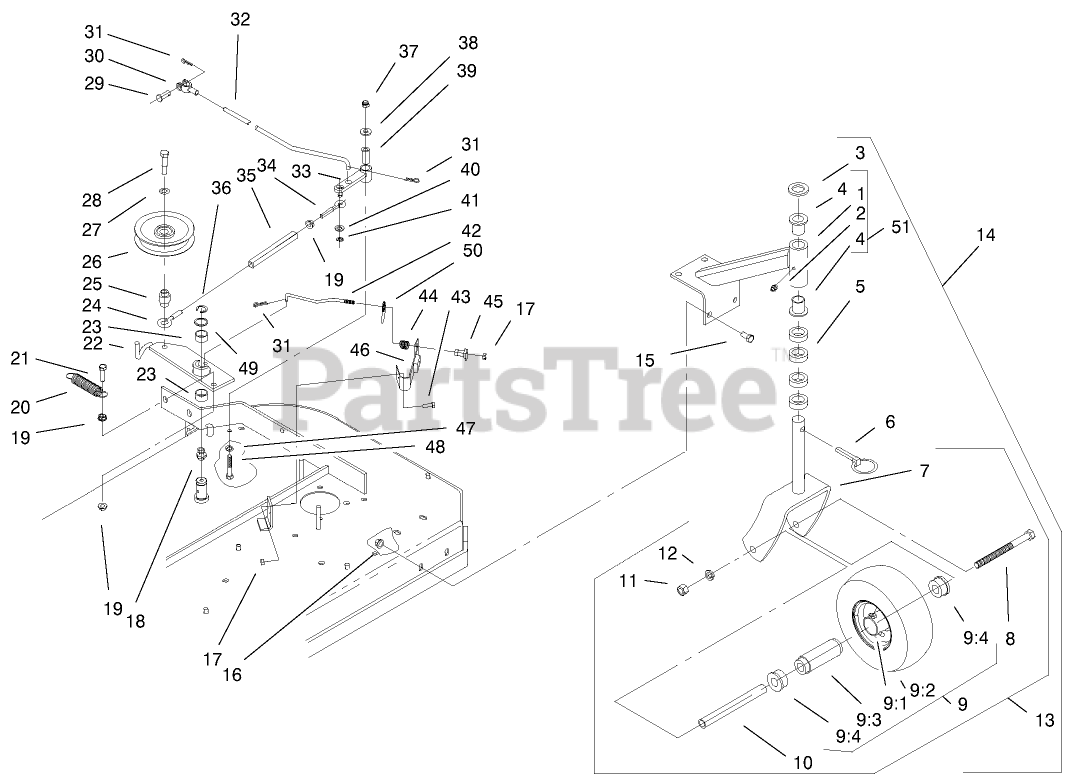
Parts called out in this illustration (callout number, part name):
1	Support-Caster
2	FITTING-GREASE
3	Washer
4	Bearing-Flanged
5	Spacer
6	Pin
7	Fork
8	SCREW-HH
9	Tire/Wheel ASM
9:1	Wheel Hub ASM
9:2	Tire
9:3	Bearing
9:4	Bushing
10	Spacer
11	NUT-HH
12	WASHER-LOCK
13	Caster Wheel ASM
14	Caster/Mount ASM
15	SCREW-HH
16	NUT-HHF, WHIZ
17	NUT-LOCK, NI
18	FITTING-GREASE
19	NUT-HF
20	Spring
21	SCREW-HH
22	Engagement Arm w/Bushings
23	Bearing-Sleeve
24	Eye Bolt
25	Bushing
26	Pulley-Idler
27	Washer
28	SCREW-HH
29	Pin-Clevis
30	Yoke
31	PIN-COTTER
32	Linkage-Assist Arm
33	Assist Arm ASM
34	Eye Bolt
35	Turnbuckle Body
36	RING-RETAINING, EXT
37	NUT-LOCK, NI
38	WASHER-FLAT
39	Tube-Pivot
40	WASHER-PLAIN
41	E-Ring
42	Rod-Brake
43	SCREW-HH
44	Spring-Compression
45	Spacer-Flanged
46	Pad/Spring ASM
47	Washer-Lock
48	SCREW-HH
49	Spindle Washer
50	Ring-Push On
51	Support-Caster Wheel
